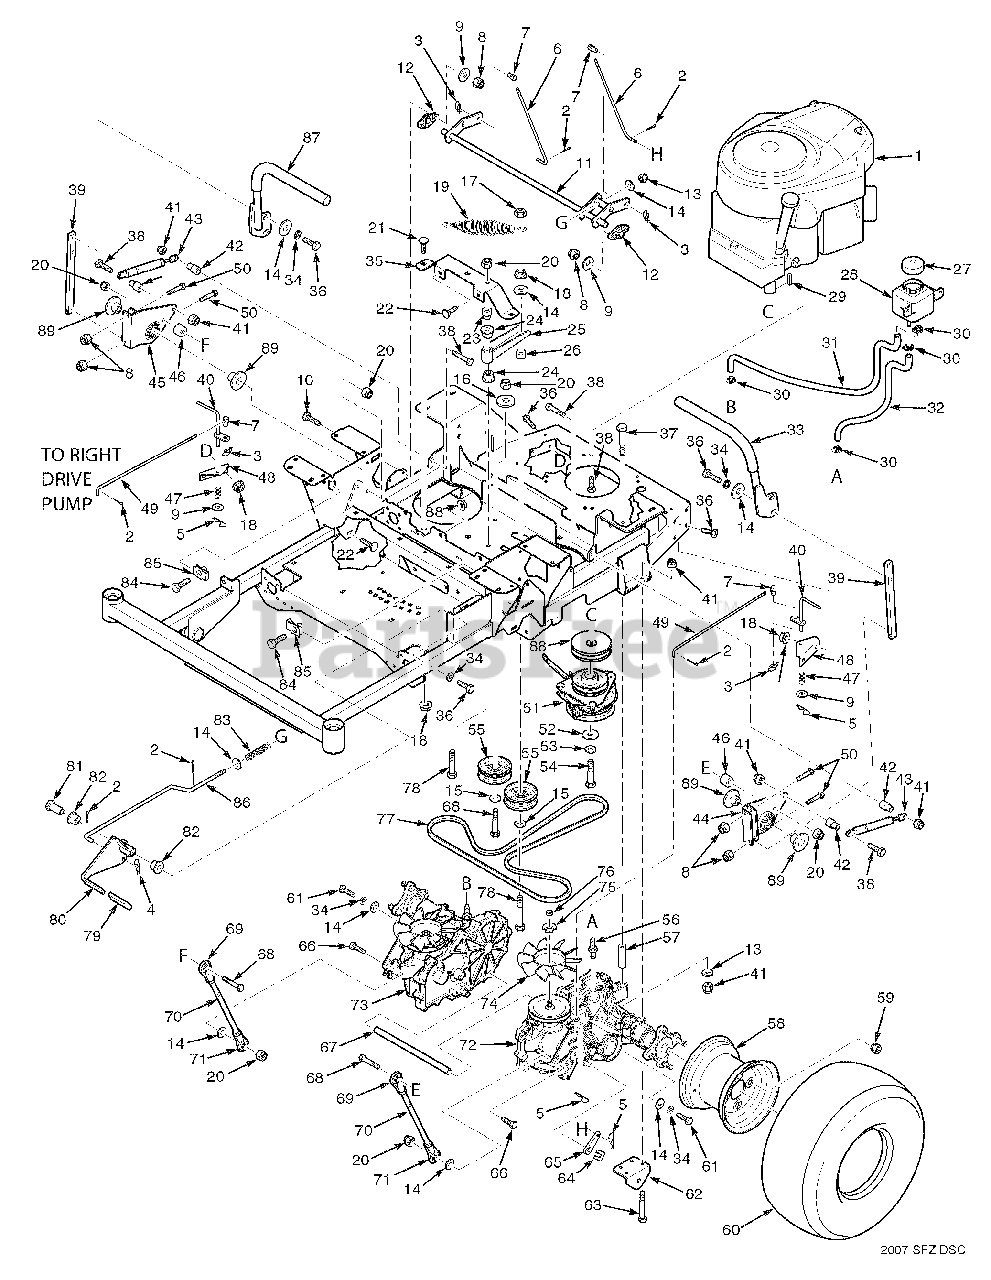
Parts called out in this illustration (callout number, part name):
1	Engine, Kawasaki 19hp
2	Cotter Pin, 3/32 x 1"
3	Pin, Rue Cotter 3/8" Dia.
4	Hair Pin Cotter, .080 x 1.19"
5	Nut, Serrated Flange 5/16-18
6	Rod, Brake Adjustment
7	Joint, Swivel
8	Nut, Elastic Stop 1/4-20
9	Flatwasher, 1/4-.312 x .750 x .065
10	Bolt, Serratted Flange 1/4-20 x 1-1/4"
11	Weldment, Brake Lever
12	Bearing
13	Flatwasher, 5/16-.375 x .875 x .083
14	Flatwasher, 3/8-.391 x .938 x .105
15	Flatwasher, 3/8-.391 x .938 x .105 HD
16	Flatwasher, 3/8-.406 x 1.5 x 7 ga.
17	Nut, Center Lock 3/8-16
18	Nut, Serrated Flange 3/8-16
19	Spring, Transmission Idler
20	Nut, Elastic Stop 3/8-16
21	Bolt, Carriage 3/8-16 x 3/4"
22	Bolt, Carriage 5/16-18 x 3/4"
23	Shaft Pivot, Idler Arm
24	Bearing
25	Transmission Idler Arm Assy.
26	Spacer, Idler Pulley
28	Reservoir Assy.
29	Key, 1/4 x 1/4 x 1-3/4"
30	Clamp, .87" Max Dia.
31	Hose, RH Transmission
32	Hose, LH Transmission
33	Handle Bar Assy. w/Grip
34	Lockwasher, 3/8" Spring
35	Support, Idler Arm
36	Bolt, Hex Head 3/8-16 x 1"
37	Bolt, Hex Head 5/16-18 x 3"
38	Bolt, Hex Head 5/16-18 x 1-1/2"
39	Bar, Control Lever
40	Dump Valve Lever
41	Nut, Elastic Stop 5/16-18
42	Spacer, Pump Dampener
43	Dampener
44	Control Linkage, LH
45	Control Linkage, RH
46	Spacer
47	Spring
48	Bracket, Dump Mounting
49	Rod, Brake Linkage
50	Bolt, Hex Head 1/4-20 x 1-1/2"
51	Electric Clutch Assy.
52	Flatwasher, 7/16-.469 x 1.75 x .25
53	Lockwasher, 7/16" Spring
54	Bolt, Hex Head 7/16-20 x 2-1/4" Patch
55	Pulley, 3-1/2" Dia.
56	Fitting, Transmission
57	Spacer, Axle
58	Rim w/Valve Stem
59	Wheel Nut, 1/2-20
60	Wheel Assy.
61	Bolt, Hex Head 3/8-16 x 2-1/4"
62	Bracket, Pusharm Link
63	Bolt, Hex Head 5/16-18 x 3"
64	Clip, Brake Lever
65	Lever, Brake
66	Bolt, Hex Head 3/8-16 x 1-1/4"
67	Spacer, Axles
68	Bolt, Hex Head 3/8-16 x 2"
69	Rod End, 3/8-24 UNF RH
70	Linkage, Pump
71	Rod End, 3/8-24 UNF LH
72	Transaxle Assy, LH
73	Transaxle Assy, RH
74	Fan
75	Fan Washer
76	Fan Nut
77	Belt, Transmission Drive
78	Bolt, Hex Head 3/8-16 x 3"
79	Grip, Brake Handle
80	Brake Handle Assy.
81	Spacer, Brake Handle
82	Bearing
83	Spring, Brake
84	Bolt, Hex Head 3/8-16 x 1-1/4 Special Lock
85	U-Nut, 3/8-16
86	Rod, Brake Linkage
87	Handle Bar w/Grip
88	Pulley, 4-1/2" Dia. 1" Bore
89	Spacer, Linkage
